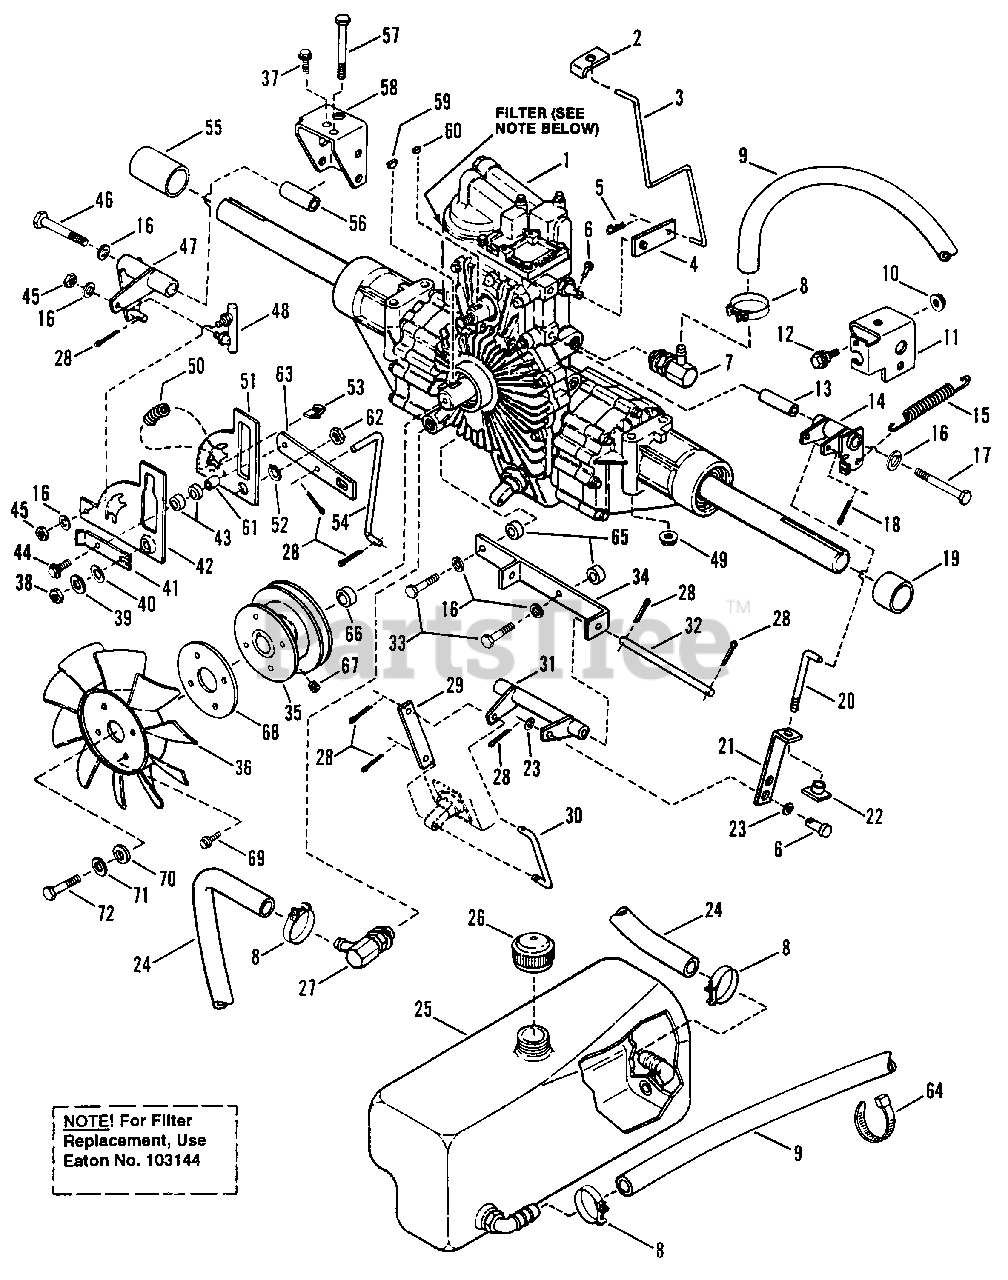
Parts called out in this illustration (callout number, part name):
1	TRANSAXLE, Hydrostatic
2	LATCH, Roll Release
3	ROD, Roll Release
4	ARM, Roll Release
5	PIN, Hair
6	PIN, 1/4 x 5/8" Clevis
7	FITTING, Hose, 90°.
8	CLAMP, Hose
9	HOSE, Supply
10	NUT, 5/16-18 Hex Flange Lock
11	BRACKET, Neutral Return
12	SCREW, 5/16-18 x 3/4" Shoulder
13	SPACER, Short
14	PIVOT, Neutral Return
15	SPRING
16	WASHER, 5/16 Split Lock
17	BOLT, 5/16-18 x 2-1/2" Hex Head
18	COTTER-PIN, 1/4 x 7/8" Self-Locking
19	SPACER, Wheel, L.H.
20	LINK, Parking Brake Adjusting
21	BRACKET, Parking Brake
22	TEE-NUT, 1/4-20
23	WASHER, 1/4 Flat
24	HOSE, Return
25	ASSEMBLY, Oil Tank
26	CAP, Oil Tank (Vented)
27	FITTING, Hose, 70°.
28	COTTER-PIN, 3/32 x 3/4"
29	RETAINER, Brake Link
30	LINK, Parking Brake
31	PIVOT, Parking Brake
32	PIN, Parking Brake Pivot
33	SCREW, 5/16-18 x 1-1/4" Hex Head
34	BRACKET, Parking Brake Pivot
35	PULLEY, Input, 3/4" Shaft
36	FAN
37	BOLT, 5/16-18 x 1/2" Hex Flange Lock
38	NUT, 3/8-16 Hex
39	WASHER, 3/8 Split Lock
40	WASHER, 3/8" Flat
41	BRACKET, Retainer
42	CAM, Neutral Return
43	ROLLER
44	BOLT, 1/4-20 x 7/8" Hex Head
45	NUT, 5/16-24 Hex
46	BOLT, 5/16-18 x 3-3/4" Hex Head
47	BELLCRANK, Speed Control
48	LINK, Shift
49	NUT, 3/8-24 Hex Flange Lock
50	SPRING
51	GUIDE, Roller
52	RING, Retaining
53	U-NUT, M6
54	LINK, Neutral Return
55	SPACER, Wheel, R.H.
56	SPACER, Long
57	BOLT, M6 Threads x 4", Adjusting
58	BRACKET, Neutral Adjusting
59	KEY, Woodruff
60	KEY, Woodruff
62	NUT, 1/4-20 Hex Center Lock
63	ARM, Neutral Return
64	TIE, Hose
65	SPACER, 5/16 x 1/2"
66	SPACER, Fan
67	SETSCREW, 5/16-18 X 5/16" Hex Socket
68	SPACER, Fan
69	SCREW, 1/4-20 x 3/4" Self-Tapping
70	WASHER, Flat
71	WASHER, Split Lock
72	BOLT, 1/4-20 x 1-1/2" Hex Head
